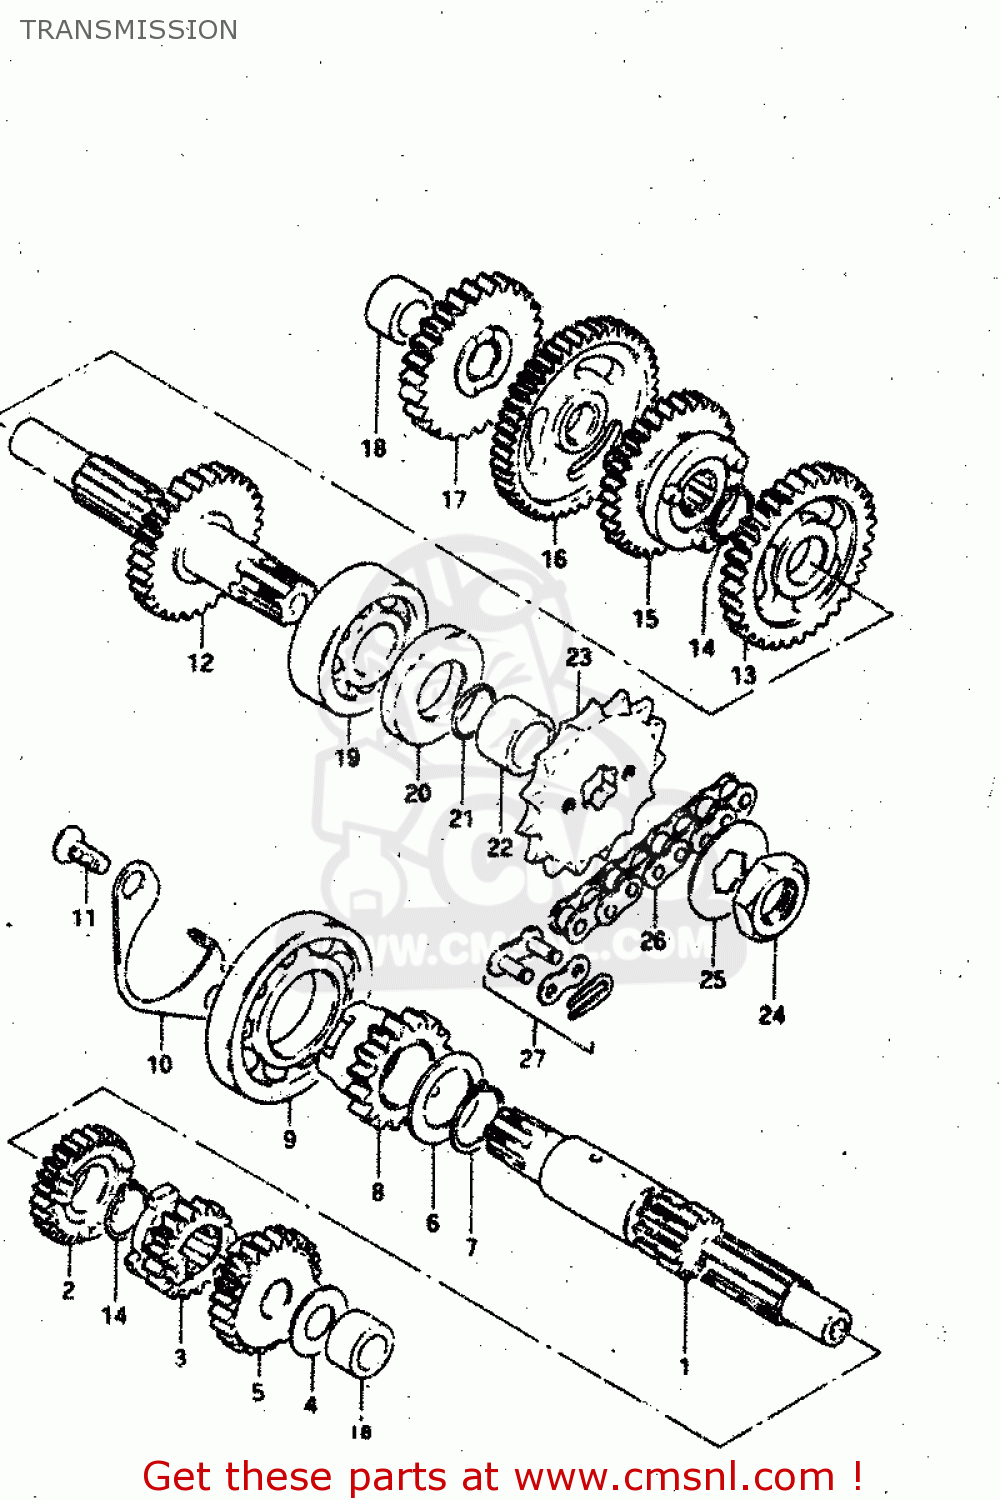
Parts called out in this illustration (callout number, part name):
1	SHAFT, COUNTER
2	GEAR, 3RD DRIVE (NT:19)
3	GEAR,2ND DRIVE(NT:15)
4	WASHER
5	GEAR, 4TH DRIVE (NT:25)
6	WASHER(21X30X1)
7	CIRCLIP,21MM
8	GEAR,KICK STARTER DRIVEN(NT:16
9	BEARING(30X62X10)
10	RETAINER,CNTR SHAFT BEARING
11	SCREW
12	SHAFT,DRIVE(NT:31)
13	GEAR, 2ND DRIVEN (NT:33)
14	CIRCLIP
15	GEAR,3RD DRIVE
16	GEAR, 1ST DRIVEN (NT:44)
17	GEAR,KICK STARTER IDLE
18	BUSH(12X19X11)
19	BEARING
20	SEAL,OIL(21X40X7)
21	O RING(D:1,ID:16.8)
22	SPACER(17X21X13)
23	SPROCKET(NT:15)
24	NUT
25	WASHER,LOCK
26	CHAIN ASSEMBLY,DRIVE
27	JOINT ASSEMBLY,CHAIN
